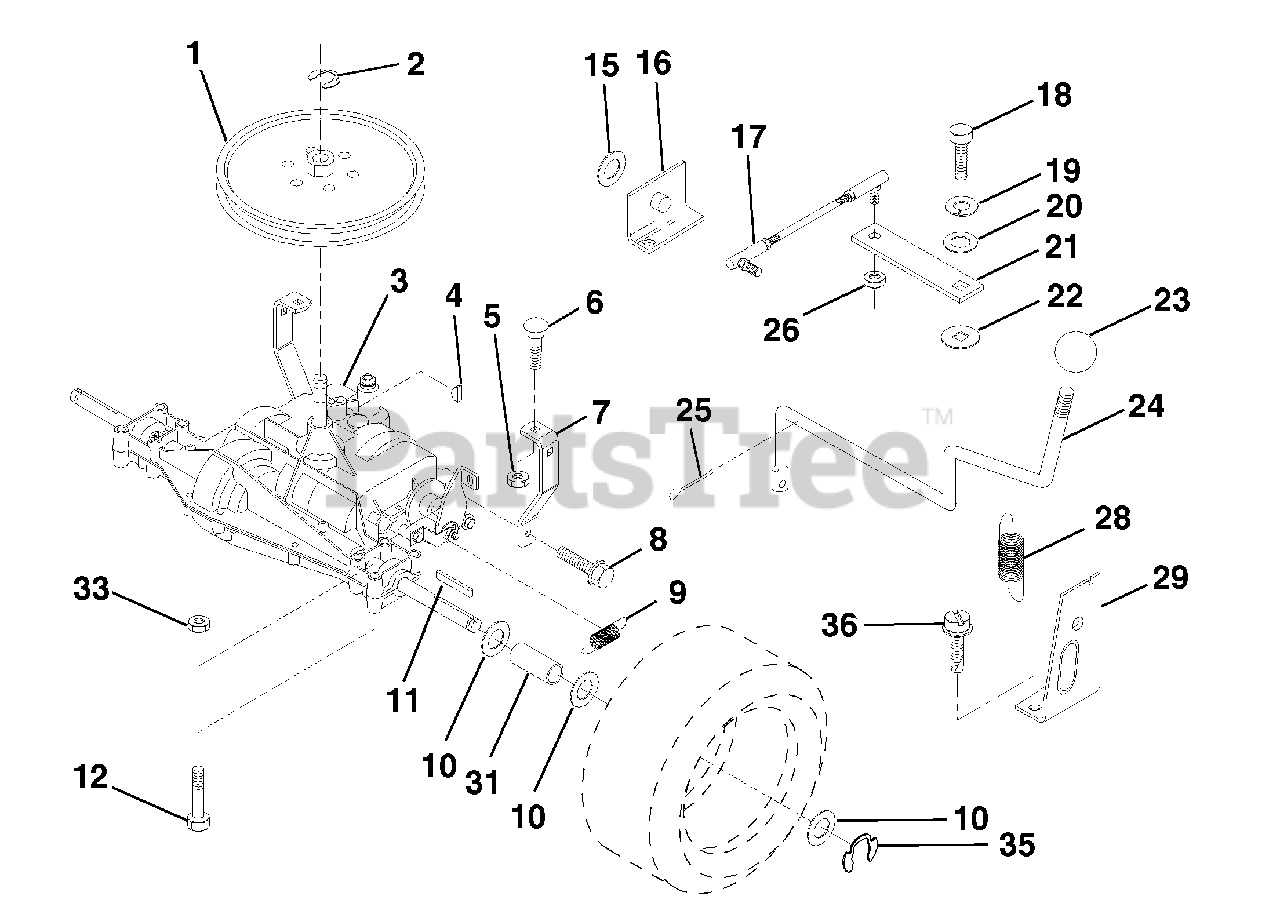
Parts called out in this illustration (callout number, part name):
2	Ring, Retainer
3	Transaxle, Dana Model No. 4360-79
4	Key, Woodruff #9
5	Nut, Crownlock 5/16-18
6	Bolt, Carriage 5/16-18 UNC x 3/4
7	Strap, Torque
8	Screw 5/16-18 x 3/4
9	Spring, Brake
10	Washer 25/32 x 1-1/4 x 16 Gauge
11	Key, Square
12	Bolt, Hex, Fin. 3/8-16 Unc x 2-3/4
15	Washer 17/32 x 1 x 16 Gauge
16	Support Handle Shift, LH
17	Link, Shift
18	Bolt, Hex, Fin. 1/4-28 UNF x 3/4 Grade 8
19	Washer, Lock 1/4
20	Washer 9/32 x 3/4 x 10 Gauge
21	Arm, Shift
22	Washer, Shift Plate
23	Knob, Duckhead
24	Rod Assembly, Shift
25	Pin, Cotter 1/8 x 1
26	Locknut 5/16-24 UNF
28	Extension, Spring
29	Support Handle Shift, RH
31	Spacer Split
33	Nut, Crownlock 3/8-16 UNC
36	Screw, Thd. Cut 1/4-20 x 1/2
